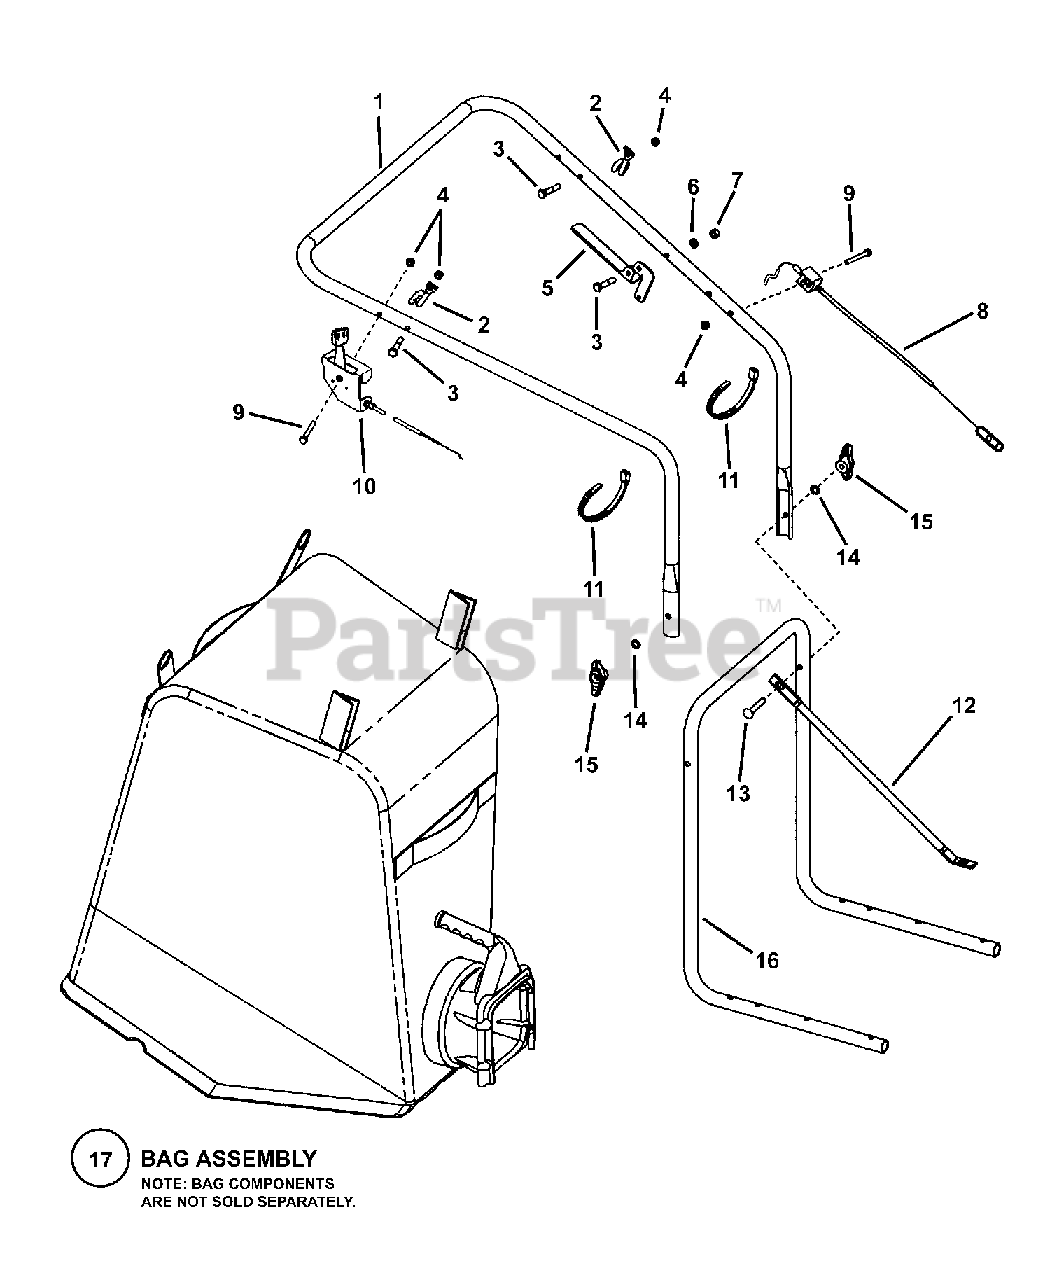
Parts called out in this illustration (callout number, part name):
1	HANDLE ASSEMBLY, Upper
2	GUIDE, Pull Rope
3	SCREW, 1/4-20 x 1-1/2" Hex Head Cap, GR 5
4	NUT, 1/4-20 Hex Nyloc
5	HANDLE, Height Adjust
6	WASHER, 5/16" Split Lock
7	NUT, 5/16-18 Hex, GR 5 or B
8	CABLE, Height Adjust
9	SCREW, 1/4-20 x 2" Hex Head Cap, GR 5
10	CABLE, Throttle, B&S
11	CABLE TIE, 7"
12	BRACE, Handle
13	BOLT, 5/16-18 x 2" Square Neck Carriage, GR 5
14	WASHER, 5/16" Internal Tooth Lock
15	KNOB, 5/16-18 Wing (Black)
16	HANDLE, Lower
17	* ASSEMBLY, Vacuum Bag
